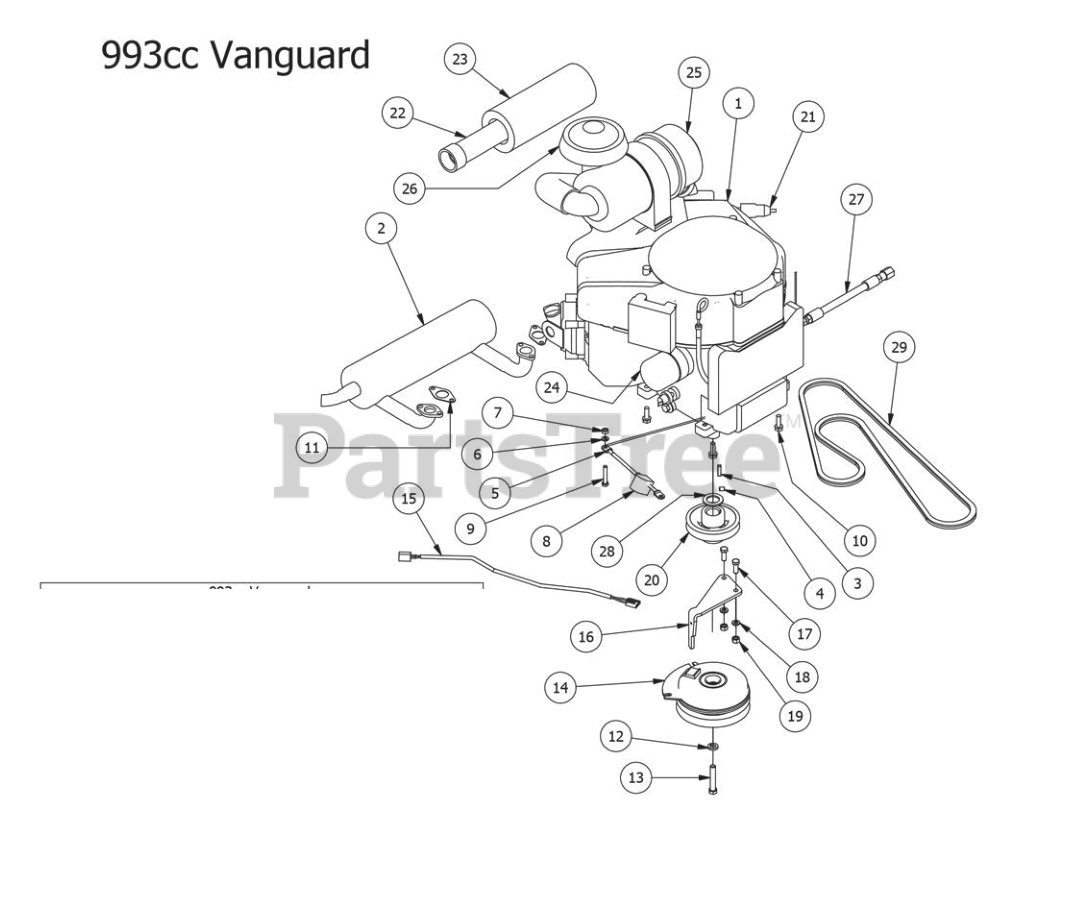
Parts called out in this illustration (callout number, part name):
1	993cc Briggs Vanguard Engine
2	Vanguard Exhaust
3	1/4" x 1" Key
4	5/16 Set Screw
5	Starter to chassis cable
6	5/16" Lock Washer
8	Black Boot For ground cable
9	5/16" x 1 3/4" Hex Bolt
10	3/8 x 1 1/8 bolt
11	Exhaust Gasket
12	7/16" Lock Washer
13	7/16" x 2 1/2" Hex Bolt
14	Clutch Assembly
15	Clutch Pigtail
16	PTO Engager Holder
17	3/8" x 1" Hex Bolt
18	3/8" Lock Washer
19	3/8" Hex Nut
20	4 3/4 Motor Pulley
21	Universal inline Fuel Filter
22	Canister Air Filter- Inner
23	Canister Air Filter-Outer
24	Briggs Oil Filter
25	Complete Canister
26	Rain Cap Fits all Canisters
27	14 mm Oil drain Hose 993cc Vanguard
28	1 1/8" Flat Spacer
